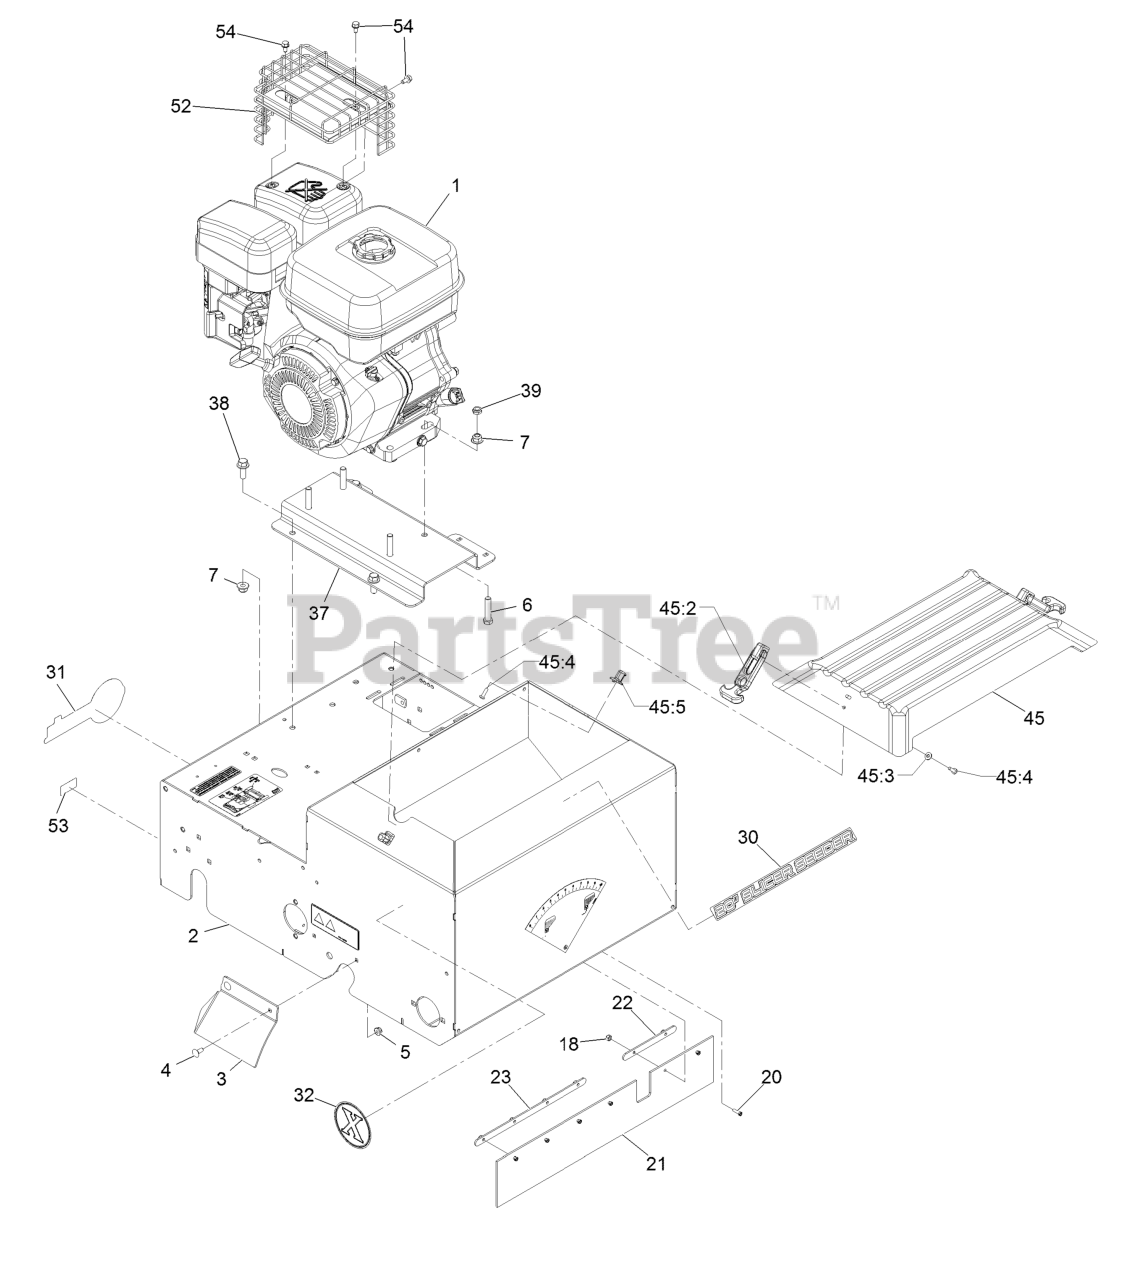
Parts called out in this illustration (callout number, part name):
2	Frame ASM
4	Bolt-Carriage 1/4-20 X 5/8
5	Nut-Nyloc 1/4-20 Flg
6	Screw-HH 3/8-16 X 1 3/4
7	Nut-Nyloc 3/8-16 Flg
18	Nut-Nyloc #8-32
20	Screw-SHH #8-32 X 5/8
21	Guard-Dust
22	Plate-Retainer
23	Plate-Retainer
30	Decal-Slicer Seeder Logo
31	Decal, Exmark Logo
32	Decal-X-Logo
37	Plate-Engine
38	Screw HHF 3/8-16 X 1
39	Nut-Nyloc 3/8-16 Thin
45	Seeder Cover Kit
45:2	Latch-Rubber
45:3	Washer-#10 Std
45:4	Screw-PPH #10-24 X 5/8
45:5	Latch-Keeper
52	Guard, Muffler
53	Decal-Patent
54	Screw-HWH M6-1 X 12Mm Tf
